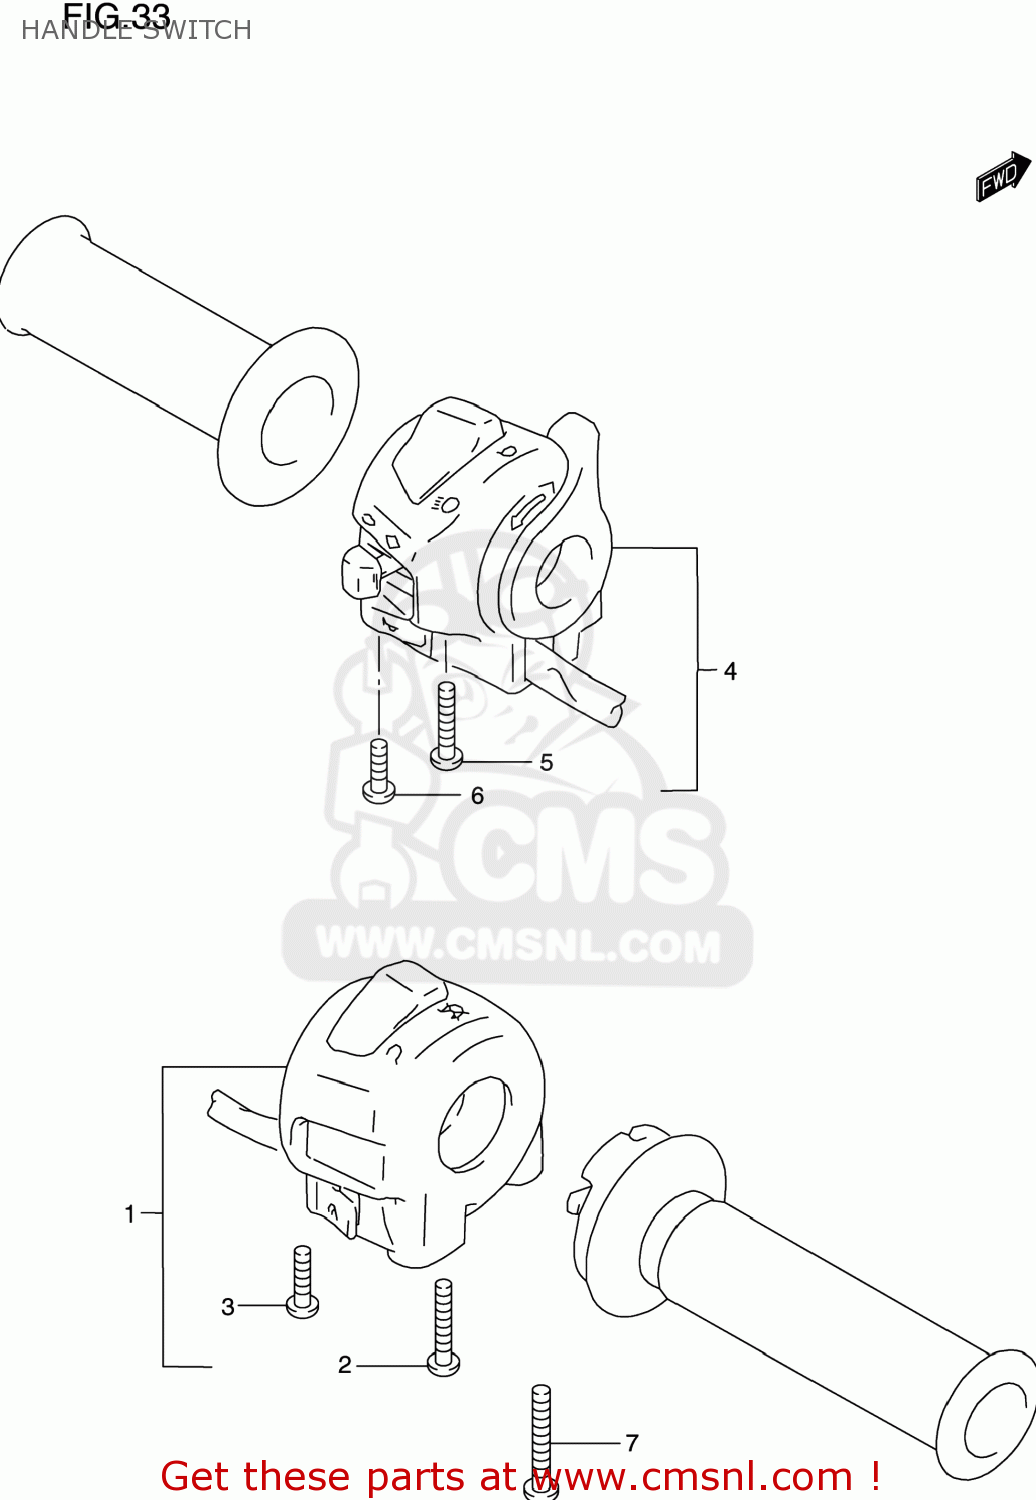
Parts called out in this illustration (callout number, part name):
1	SWITCH ASSY,HANDLE,R
2	SCREW
3	SCREW
4	SWITCH ASSY,HANDLE,L
5	SCREW
6	SCREW, 5X45
7	SCREW
